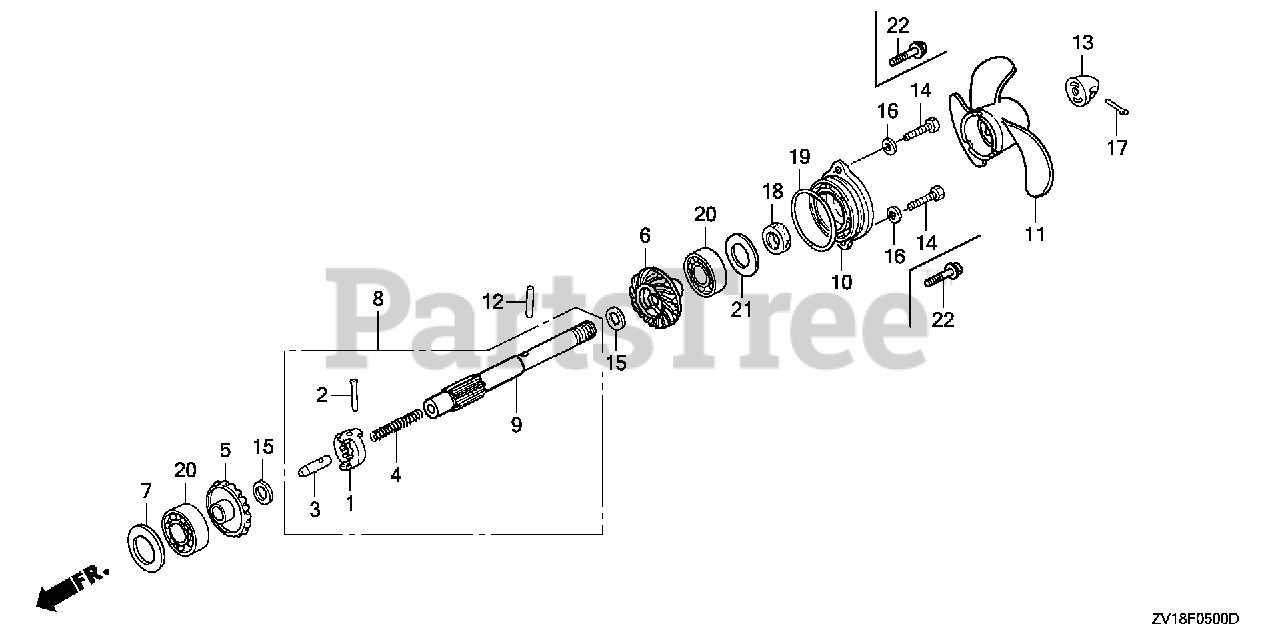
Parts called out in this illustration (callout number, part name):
1	SHIFTER, CLUTCH
2	PIN, SHIFTER (3X26)
3	SLIDER, SHIFT
4	SPRING, SHIFT
5	GEAR, BEVEL (F)
6	GEAR, BEVEL (R)
7	SHIM B, GEAR (0.10MM)
7	SHIM C, GEAR (0.15MM)
8	SHAFT, PROPELLER
9	SHAFT, PROPELLER
10	HOLDER, PROPELLER SHAFT *NH282MU* (OYSTER SILVER METALLIC-U)
11	PROPELLER, THREE-BLADE (7-7/8X7-1/2) *NH283* (STIN GRAY)
11	PROPELLER, THREE-BLADE (200X190) *NH283* (STIN GRAY)
11	PROPELLER, THREE-BLADE (200X170) *NH283* (STIN GRAY)
12	PIN, SHEAR
13	CAP, PROPELLER
14	BOLT, HEX. (6X18)
15	WASHER (13MM)
16	WASHER, PLAIN (6MM)
17	PIN, SPLIT
18	SEAL, WATER (13MM) (ARAI)
19	O-RING (52MM)
20	BEARING, RADIAL BALL (6004)
